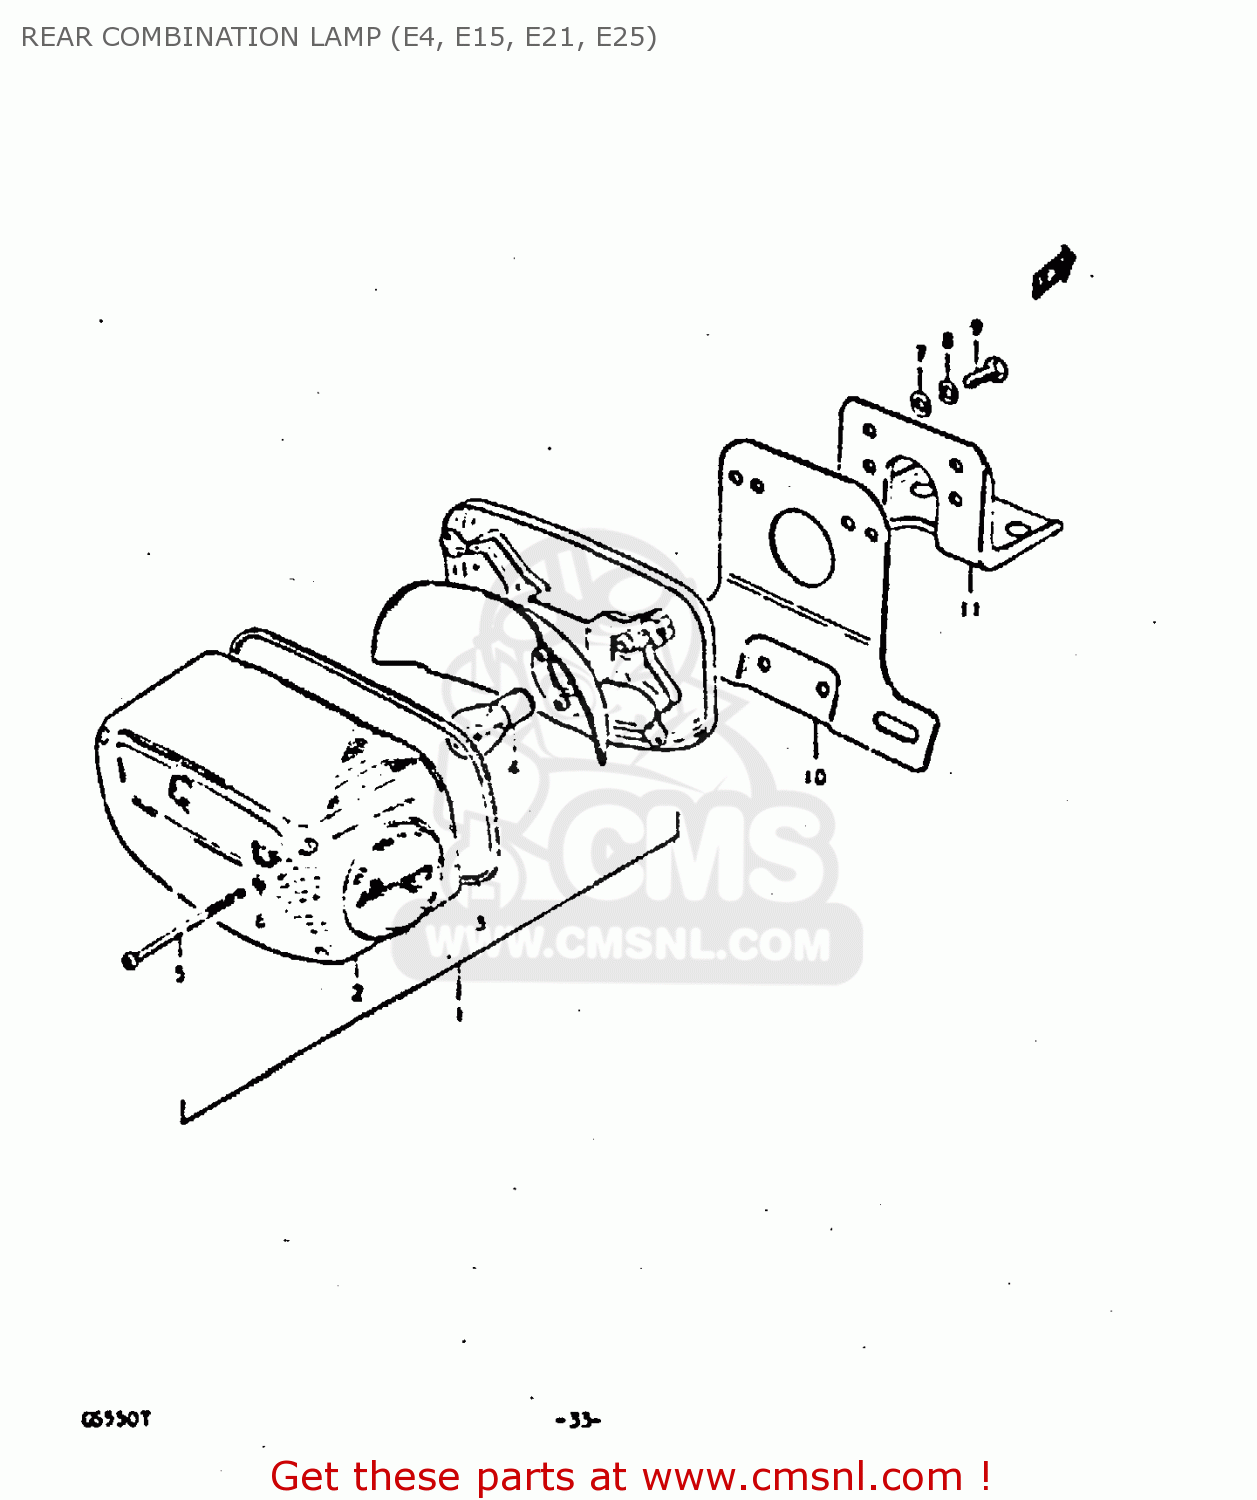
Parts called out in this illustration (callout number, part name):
1	LAMP ASSY, REAR COMBINA
2	LENS
3	GASKET (NAS)
4	BULB 12V21/5W
5	SCREW
6	GASKET (NAS)
7	WASHER
8	LOCK WASHER
9	BOLT
10	BRACKET,LICENSE PLATE
11	BRACKET,LICENSE PLATE
